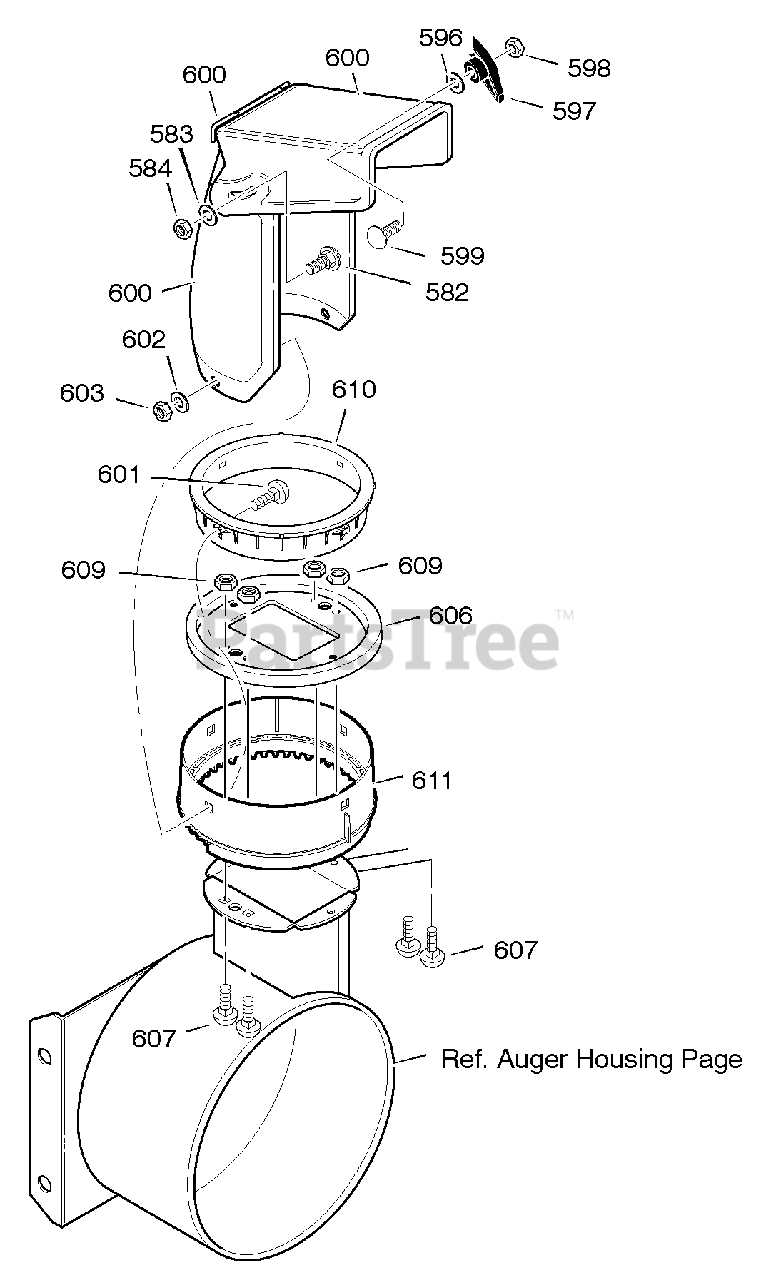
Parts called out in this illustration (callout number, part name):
582	SCREW, 5/16-18 x 1.50
583	WASHER, FLAT
584	NUT, 5/16-18
596	WASHER
597	KNOB, T 3.00
598	NUT, 5/16-18
599	BOLT, 5/16-18x1.00
600	CHUTE ASSEMBLY
601	BOLT, 5/16-18x1.00
602	WASHER, FLAT
603	NUT, 5/16-18
606	CHUTE COLLAR
607	SCREW, 1/4-20 X 0.75
609	NUT, 1/4-20 HEX NYLOCK
610	RETAINER RING INNER
611	RETAINER RING OUTER
